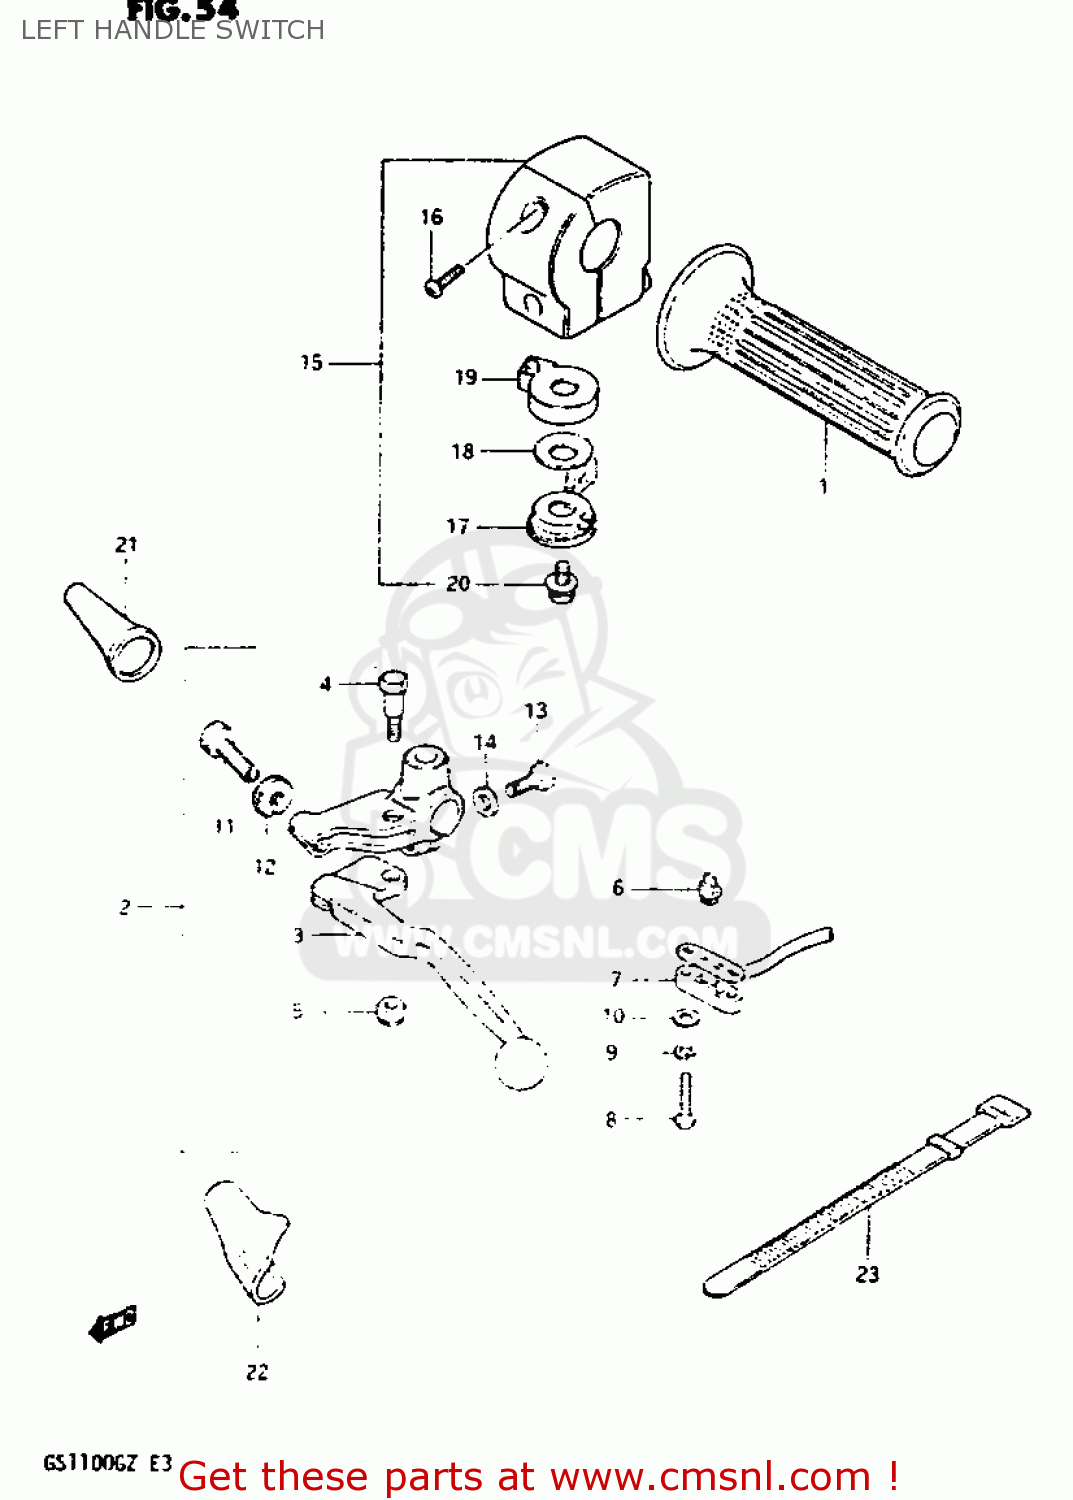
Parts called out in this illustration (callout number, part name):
1	GRIP,L
2	LEVER ASSEMBLY
3	LEVER,CLUTCH
4	BOLT,LEVER PIVOT
5	NUT 6MM
6	CONTACT,SWITCH
7	COVER,FR BK TERMINAL BASE
8	SCREW
9	WASHER,LOCK
10	WASHER
11	ADJUSTER,CABLE
12	NUT,CABLE ADJUSTER
13	BOLT
14	WASHER
15	SWITCH ASSEMBLY,HANDLE,LEFT
16	SCREW
17	LEVER,STARTER
18	WASHER,ADJUSTER
19	BODY,STARTER LEVER
20	SCREW,CHOKE LE
21	BOOT,CLUTCH CABLE
22	COVER,CLUTCH LEVER
23	CLAMP(L:120)
